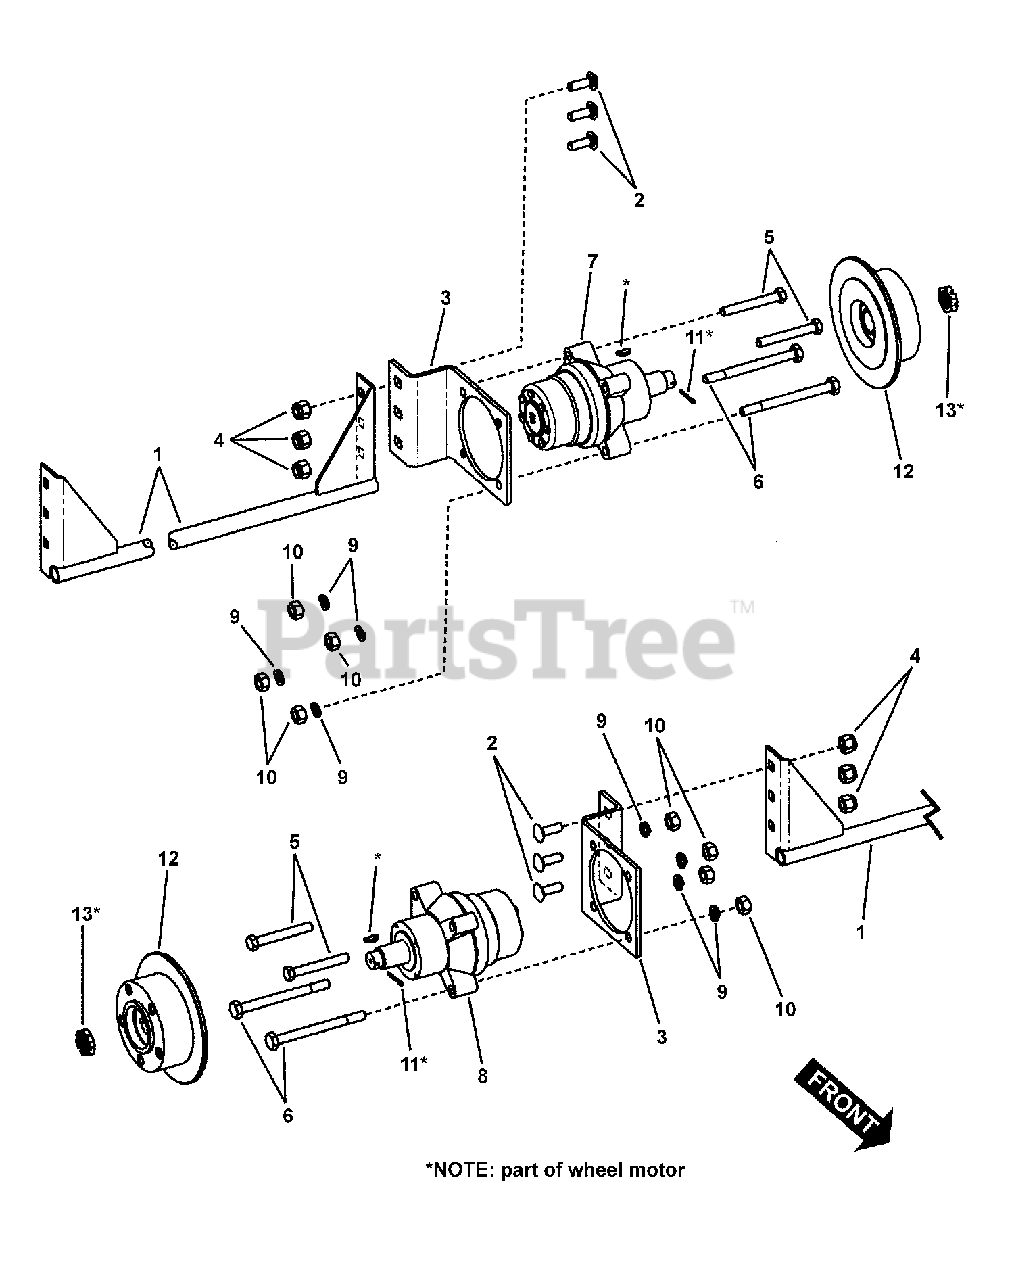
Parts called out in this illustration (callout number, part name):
1	WELDMENT, Rear Support
2	BOLT, 1/2-13 x 1-1/2" Square Neck Carriage, GR 5
3	BRACKET, Wheel Motor Support
4	NUT, 1/2-13 Hex Nyloc
5	BOLT, 1/2-13 x 3-3/4" Hex Head Cap
6	BOLT, 1/2-13 x 6" Hex Head Cap GR 5
7	WHEEL MOTOR, LH HGM 18E-3052
8	WHEEL MOTOR, RH HGM 18E-3056
9	WASHER, 1/2" Split Lock
10	NUT, 1/2-13 HEX
11	COTTER PIN, 1/8 x 1-1/4"
12	DRUM, Brake (Ausco)
13	CASTLE NUT, 1-14 UNF, GR B
